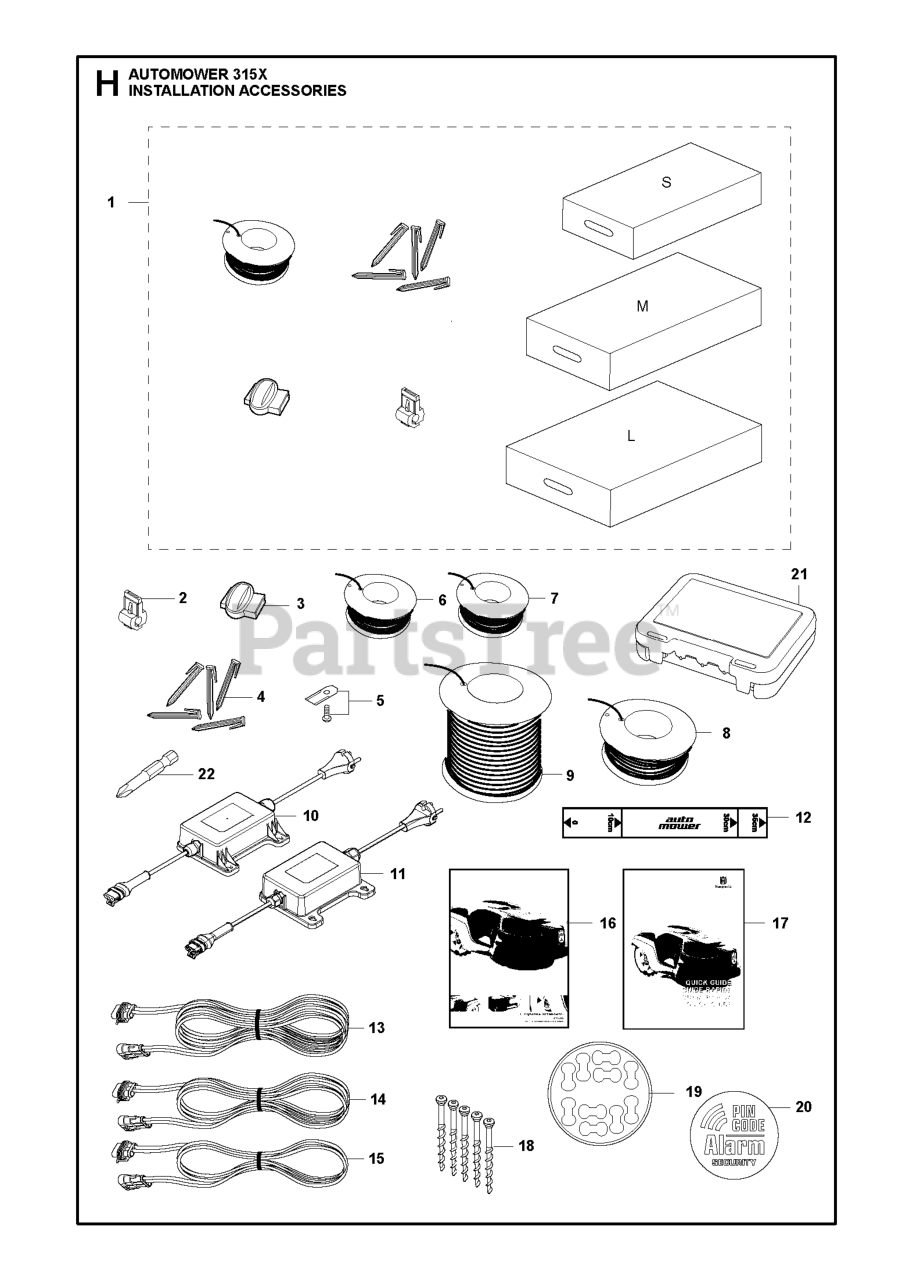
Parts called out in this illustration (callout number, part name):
1	LARGE AUTOMOWER INSTALL KIT
1	MED AUTOMOWER INSTALL KIT
1	SMALL AUTOMOWER INSTALL KIT
2	BRAKER
2	CONNECTOR 100 PCS
2	CONNECTOR 5 PCS, BLISTER
3	COUPLER SPLICER, 5 PCS,
3	COUPLER SPLICER, 100 PCS
3	SPLICE KIT
4	STAPLE 100 PCS
5	HUS BLADE SET 9 PCS
5	HUS BLADE SET 300 PCS
5	HUS BLADE SET 45 PCS
6	WIRE BOUNDARY 150M
6	WIRE 50M STANDARD Ø2.7MM,BLIST
6	WIRE 150M, BLISTER
7	WIRE 250M
8	WIRE 500M
9	WIRE (800M)
10	POWER UNIT POWER SUPPLY 1,3A
11	POWER UNIT US
12	RULER / CENTIMETERS
13	CABLE ASSY LOW VOLTAGE CABLE
14	CABLE ASSY LOW VOLTAGE CABLE
15	CABLE ASSY LOW VOLTAGE CABLE
18	SCREW KIT ANCHOR SCREW 5 PCS
19	STICKER CABLE MARKERS KIT 10PC
20	LABEL SECURITY
21	CONNECTOR PROTECTION BOX
22	WRENCH BITS CHANGING ROBOTIC B
